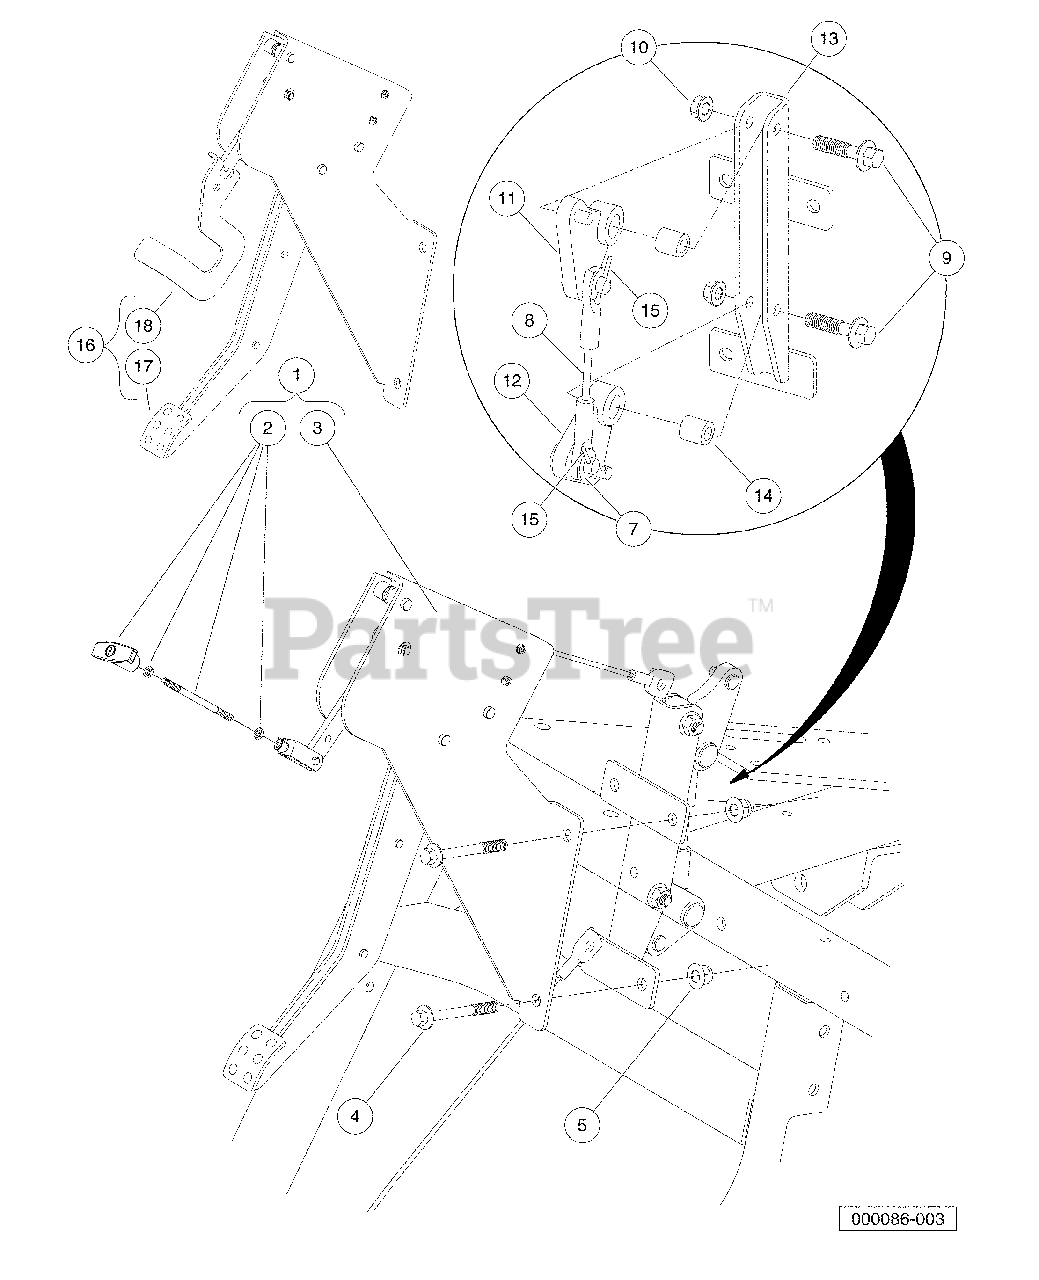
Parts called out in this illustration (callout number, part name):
1	Pedal Asm, Brake, Park
2	Kit, Handle, Brake, Park
3	Pedal, Brake, Park
4	Bolt Flanged Head, M8 X 1.25 X 65
5	Lock Nut, Flg M8 X 1.25 Nylon
6	Asm, Sub, Bracket, Park Brake
7	Washer, Flat, 3/8, Blk Fin
8	Cable, Crank, Bell
9	Bolt Flg, M8x1.25 X 35, Gr10.9
10	Nut Flg M8 X 1.25 Gr 10.
11	Asm, Bellcrank, Upper
12	Asm, Bellcrank, Lower
13	Brkt, Bellcrank, Prk Brk, Awd
14	Spacer, Pivot, Park Brk, Awd
15	Pin, 3/32 X 1.00 Sq Cut Cotter
16	Asm, Pedal, Brake, Hard
17	Pedal, Brake, Park
18	Handle, Release, Park Brake
